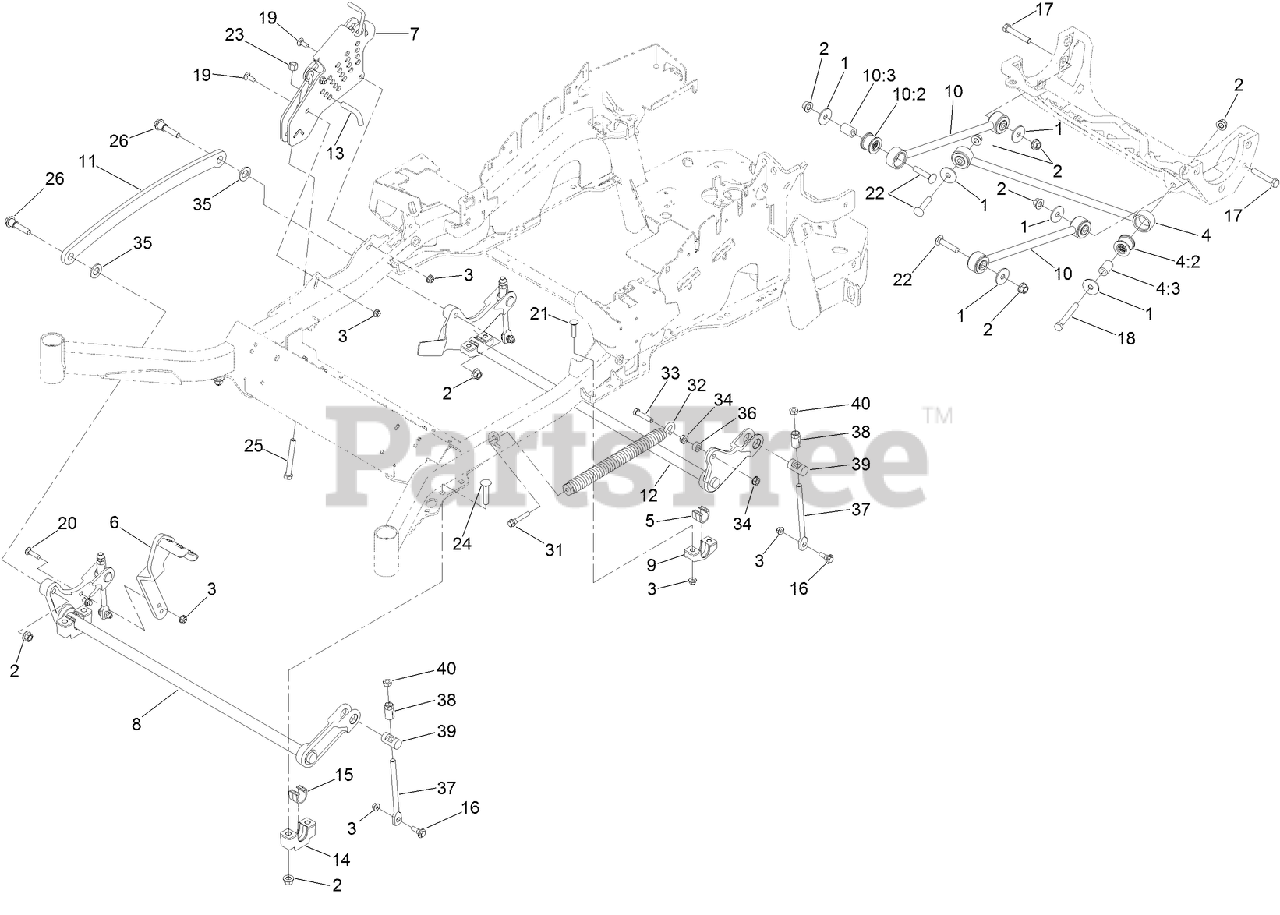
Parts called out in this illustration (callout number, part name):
1	WASHER-THRUST
2	NUT-LOCK
3	NUT-HF, NI
4	PANHARD ROD ASM
4:2	BUSHING-SUSPENSION, RUBBER
4:3	SPACER
5	BEARING-CROSS SHAFT, REAR
6	LEVER-FOOT
7	HOC ASM
8	DECKLIFT-FRONT
9	SUPPORT-CROSS SHAFT, REAR BEARING
10	DECK STRUT ASM
10:2	BUSHING-SUSPENSION, RUBBER
10:3	SPACER
11	LINK-LIFT, DECK
12	LIFT-DECK, REAR
13	PIN-HOC
14	SUPPORT-CROSS SHAFT, BEARING
15	BEARING-CROSS SHAFT, FRONT
16	SCREW-SHOULDER, HHF
17	SCREW-HH
18	SCREW-HH
19	BOLT-CARR
20	SCREW-CARR
21	SCREW-CARR
22	SCREW-CARR
23	NUT-LOCK, NI
24	BOLT-CARR
25	BOLT-TAP
26	SCREW-HHF, SHOULDER
31	BOLT-SHOULDER
32	SPRING-EXTENSION
33	SCREW-HH
34	NUT-HF
35	WASHER-FLAT
36	SPACER
37	LINK-ADJUSTER, DECK LIFT
38	ADJUSTER-LIFT, DECK
39	TRUNNION
40	NUT-JAM
